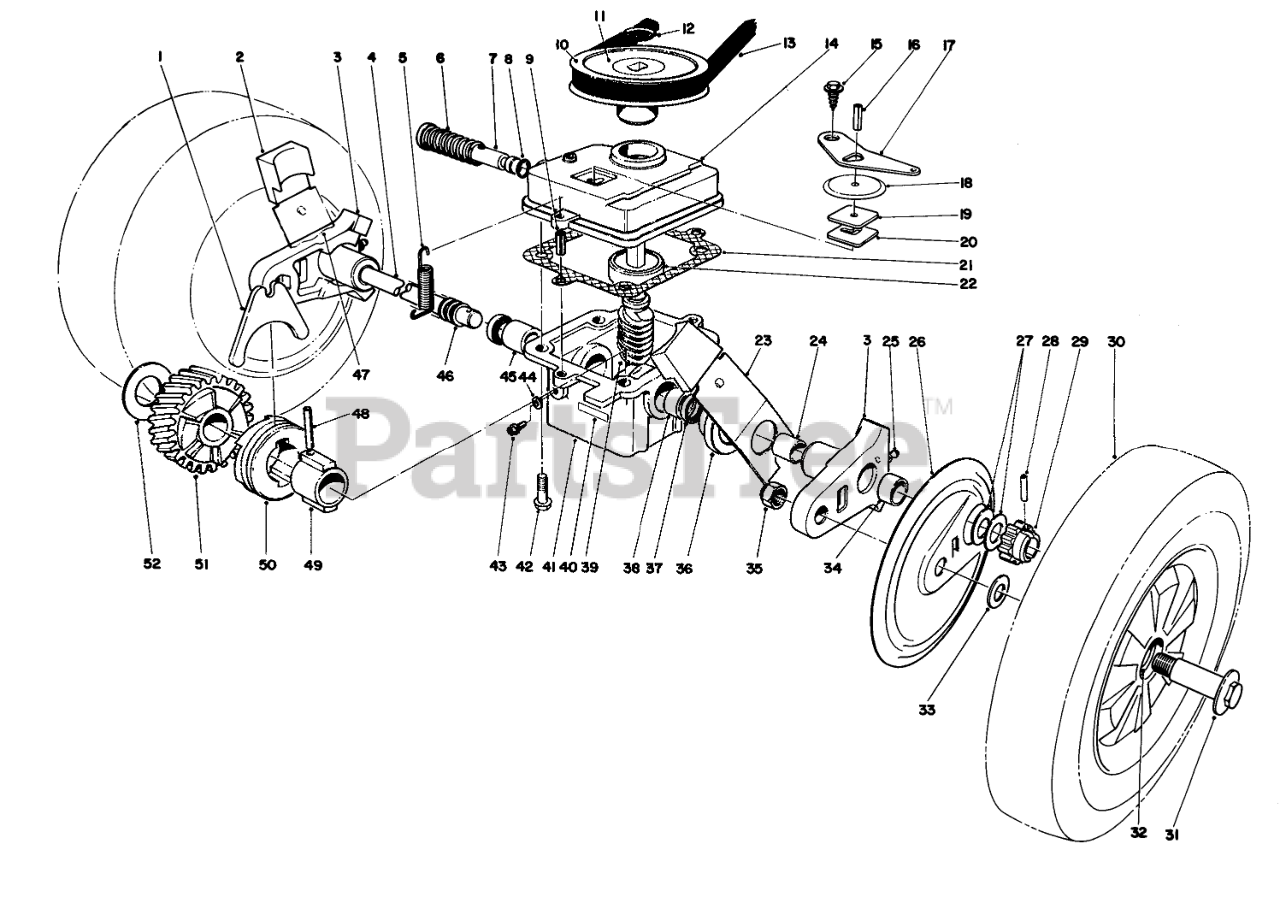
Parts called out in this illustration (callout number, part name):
2	KNOB-ARM
3	Pivot Arm (Incl. Ref. #24, 25 & 34)
4	DRIVE SHAFT (SERVCE)
5	TENSION SPRING
6	SPRING
7	SHIFTER ROD
8	O-RING
9	3/16 X 1/2 ROLL PIN
10	PULLEY
11	DECAL
12	PUSH-ON 93-3236
13	V BELT
14	GEAR CASE COVER
15	Screw
16	SPIROL PIN H D
17	SHIFTER ARM
18	DUST COVER
19	DUST FILTER
20	LATCH PLATE
21	GASKET
22	BEARING
23	SPRING ARM ASM SP LH
24	BUSHING
25	FITTING-GREASE
26	WHEEL COVER
27	THRUST WASHER
28	Pin
29	PINION GEAR 14T
30	Wheel, Tire & Gear Assembly (Incl. Ref. #32)
31	WHEEL BOLT
32	BUSHING
33	WASHER
34	BUSHING
35	Nut
36	CAP-END
37	SEAL-OIL
38	BUSHING
39	Worm Shaft & Gear (Incl. Ref. #51)
40	DECAL
41	Gear Case (Incl. Ref. #37, 38 8 45)
42	Screw
43	NYLON SCREW
44	FILL PLUG GASKET
45	BUSHING
46	COVER-SHAFT, DRIVE
47	SPRING ARM ASM SP RH
48	COIL PIN
49	SLEEVE
50	CLUTCH JAW
51	Helical Gear
52	THRUST WASHER
